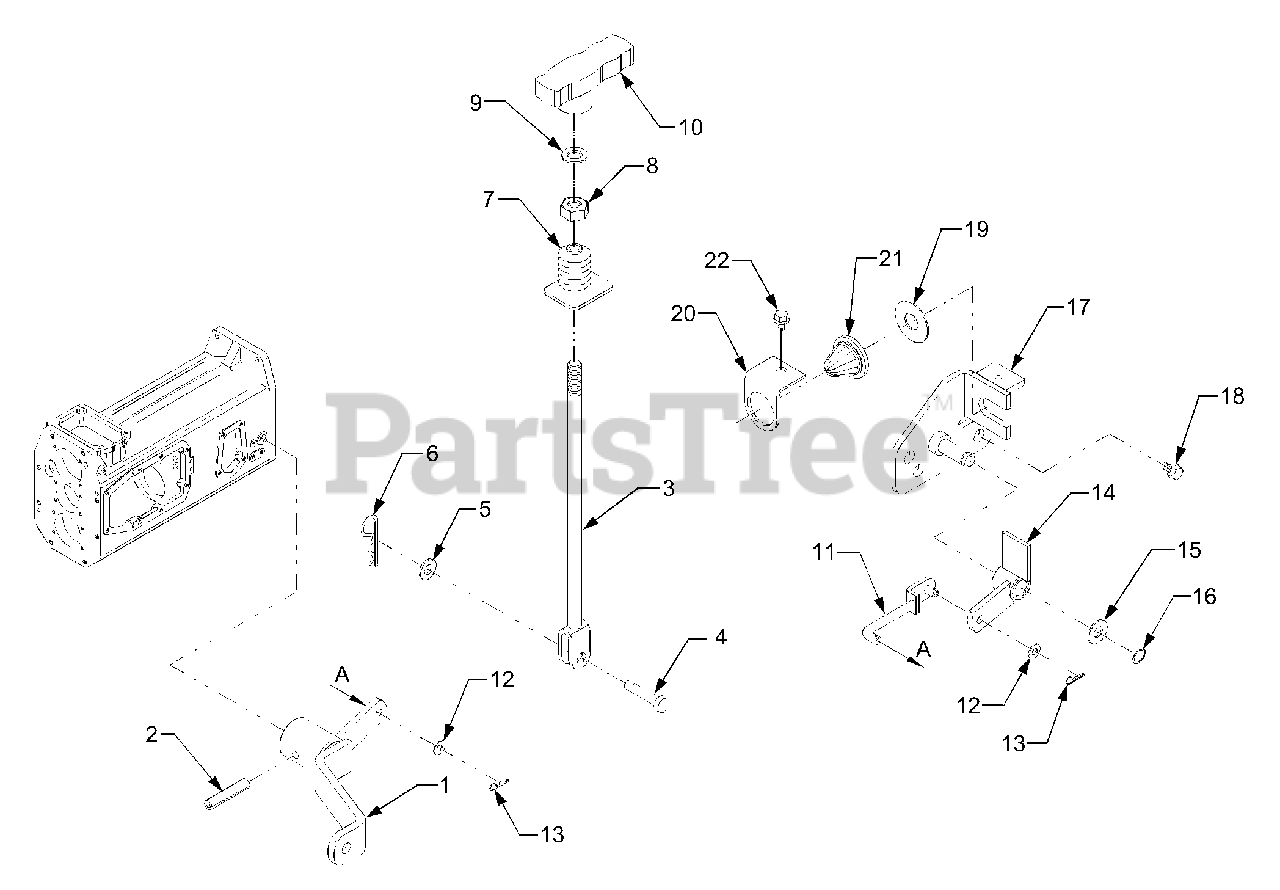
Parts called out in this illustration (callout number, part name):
1	Lever 1, Front Drive
3	Lever 2, Front Drive
5	Washer, Plain
9	Washer, Plain
10	Grip
11	Rod (Front Drive)
12	Washer, Plain
14	Lever, Switch
15	Washer, Plain
17	Bracket, Switch
20	Bracket (Switch)
21	Cover (Switch)
